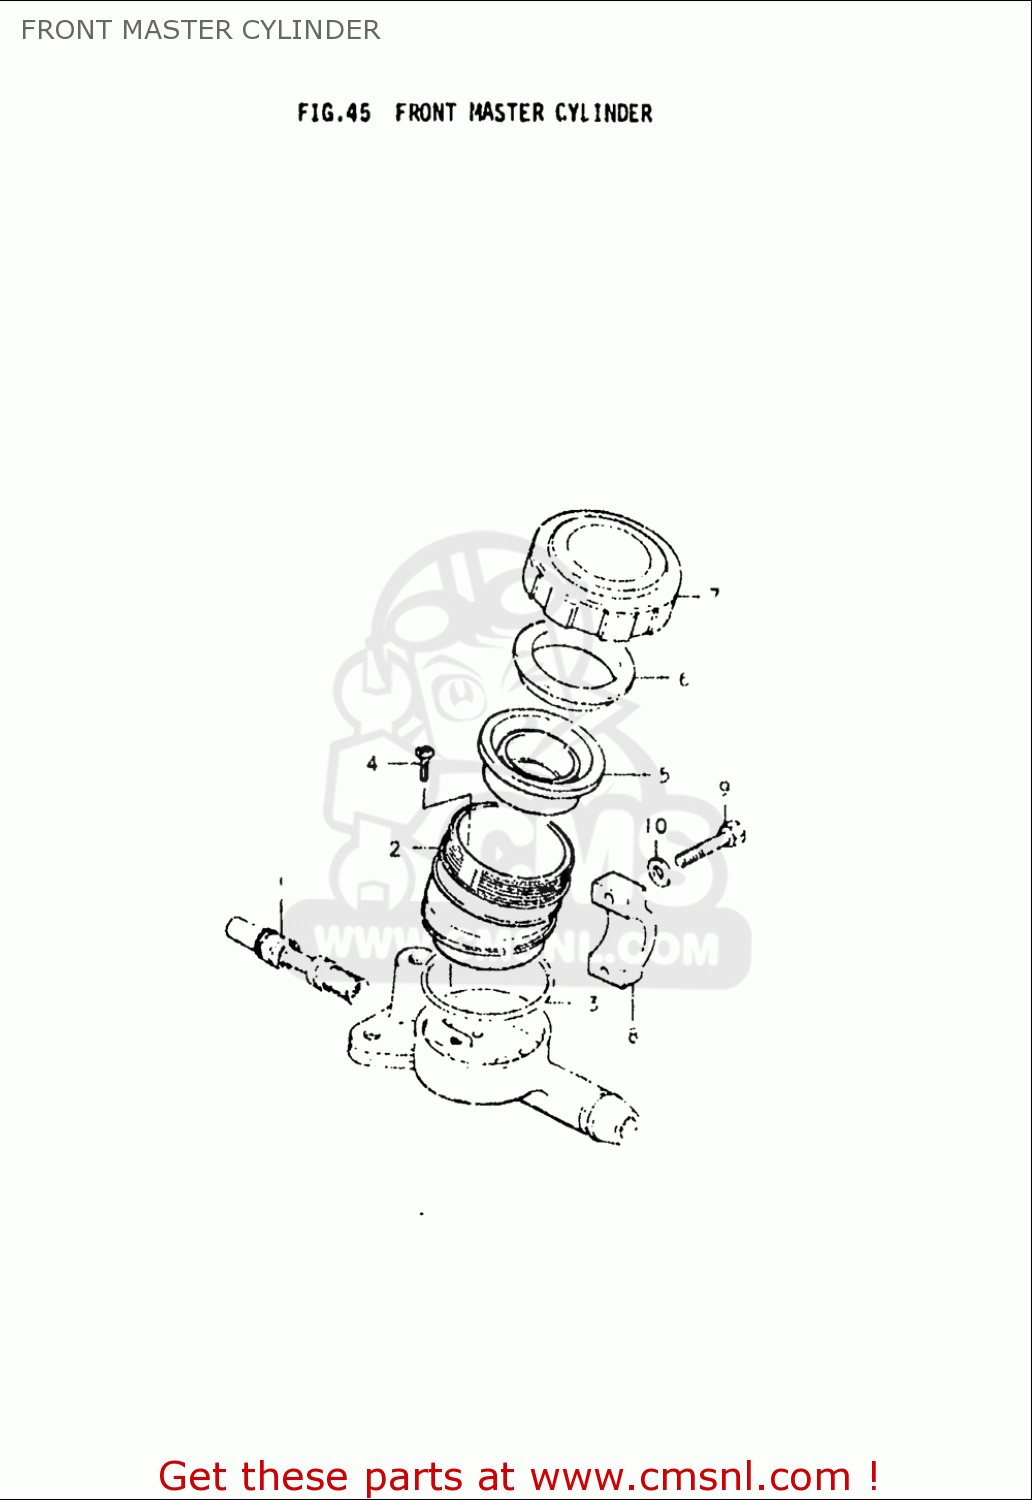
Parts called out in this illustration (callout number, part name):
1	PISTON & CUP SET
2	RESERVOIR
3	O RING
5	DIAPHRAGM
6	PLATE
9	BOLT
10	WASHER
